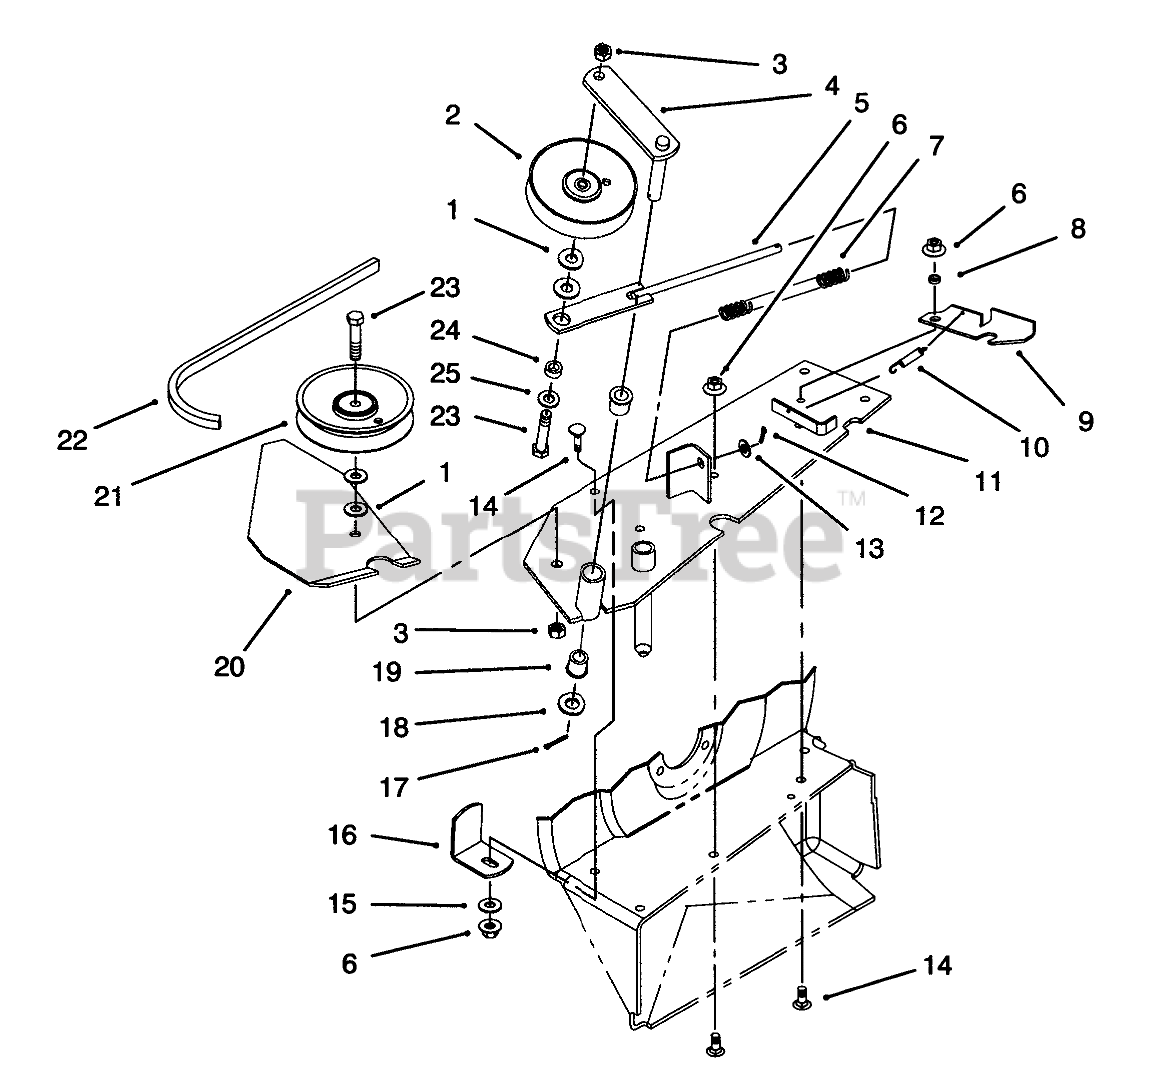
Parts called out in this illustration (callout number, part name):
1	WASHER-FLAT
2	PULLEY-IDLER
3	NUT-LOCK, NI
4	IDLER ARM ASM
5	SPRING-ROD
6	NUT-HF
7	SPRING-COMPRESSION
8	BUSHING
9	LATCH - BLOWER B
10	SPRING-EXTENSION
11	BLOWER MOUNTING-WELDED B
12	PIN-COTTER
13	WASHER-PLAIN
14	SCREW-CARR
15	WASHER-FLAT
16	BRACKET-SUPPORT, HOUSING
17	PIN-COTTER
18	WASHER-FLAT
19	BUSHING
20	SHIELD SUPPORT B
21	PULLEY-IDLER
22	BELT-V
23	SCREW-HH
24	SPACER
25	WASHER-FLAT
